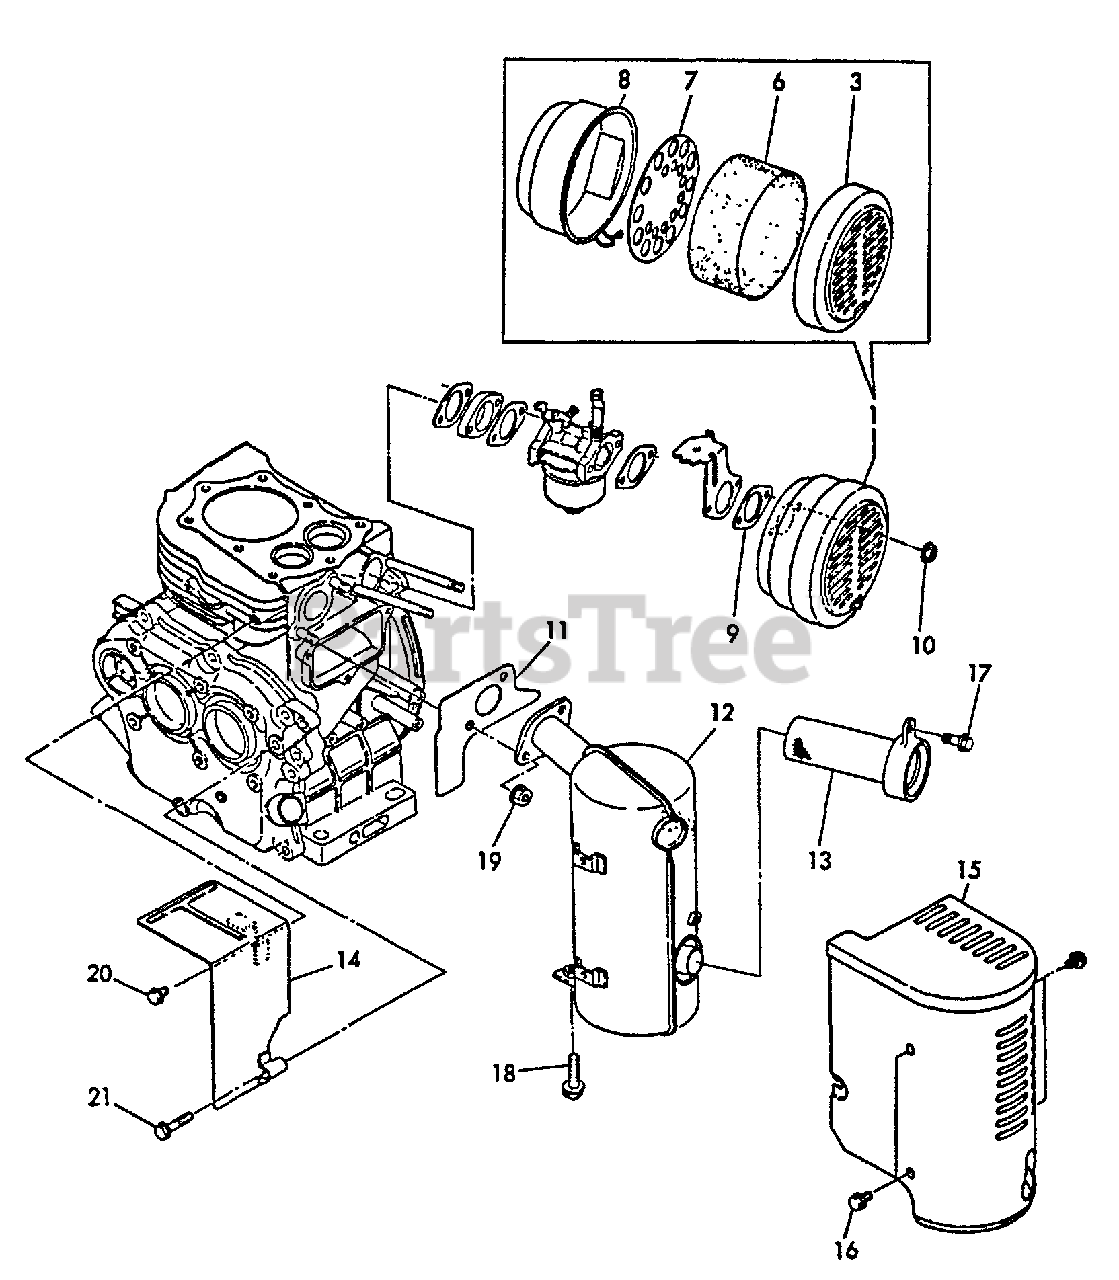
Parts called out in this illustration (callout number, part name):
1	AIR CLEANER ASSY
3	CASE, AIR FILTER
6	FILTER, AIR
7	HOLDER, ELEMENT
8	COVER, AIR FILTER
9	GASKET, INTAKE
10	NUT - 6 -- FLANGE
11	GASKET, EXHAUST
12	MUFFLER
13	SCREEN, SPARK ARRESTOR
14	PLATE, GUIDE
15	COVER, MUFFLER
16	BOLT - 6X8 -- PLATED
17	BOLT - 6X10 -- PLATED
18	BOLT - 8X30 -- PLATED
19	NUT - 8
20	BOLT - 6X8 -- PLATED
21	BOLT - 6X30
